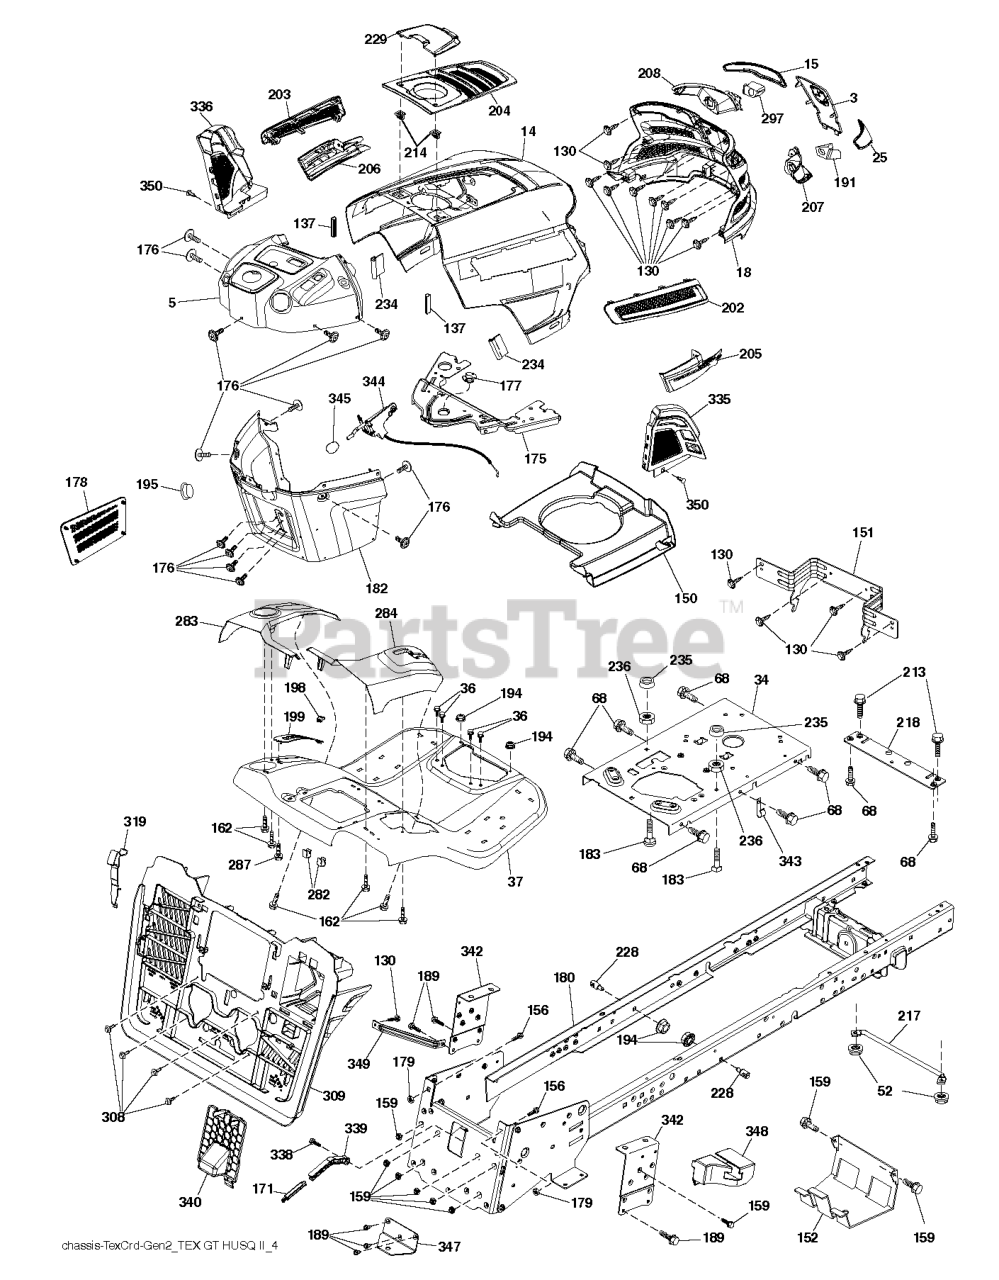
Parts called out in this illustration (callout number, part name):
3	APPLIQUE.SUBASM.GT.HUSQ.II
5	DASH.UPP.GT2.SM.PTO.MC.HR.GREY
14	HOOD.ASM.HUSQVARNA.GT.TEX.ORAN
15	LENS.HEADLIGHT.LH.GTII.2011
18	GRILLE.SUBASM.GT.HUSQ.II
25	LENS.HEADLIGHT.RH.GTII.2011
34	PLATE.ENGINE.WELDED.CHASSIS
36	SCREW 5/16"
37	FENDER.TEX.SRD.CRD.BASE
52	LOCKNUT
68	SCREW LT
130	SCREW.#10 X 0.750.BOS
137	BUMPER DASH
150	AIR DUCT.GTV2(1.66"RING HEIGHT
151	BRACKET.PIVOT.HOOD.GT.HUSQ.II
152	SHIELD.BROWNING.PNT.GT.V2
156	BOLT
159	SCREW, 3/8-16X3/4
162	SCREW.HI-LO.CONSOLE
171	EXTENSION.BAGGER.FULL.
175	PLATE.CROSSMEMBER.HUSQ
176	SCREW.#10-24X5/8.RN.QU
177	BUSHING, STEERING
178	CARGO.ASM.NET.TXGT.W/C
182	DASH DASH LOWER
183	BOLT.5/16-18X1-1/4 FULL THD
189	SCREW
191	INSERT.REFLECTIVE.RH.HUSQ.GTII
194	NUT LOCK HEX FLANGE 5/16-18
195	PLUG.HOLE.DASH.LOWER.12V.BLK
198	INDICATOR.DECK.LIFT.RED
199	PLATE DECK LIFT
202	VENT.SIDE.RH.GT.HUSQ.II.
203	VENT.SIDE.LH.GT.HUSQ.II.498
204	VENT.TOP.EXTERNAL.FILL.GT2.GRE
205	SIDE.TRIM.RH.GT.HUSQ.II
206	SIDE.TRIM.LH.GT.HUSQ.II.GRAY
207	BEZEL LIGHT.RH.GT.II.MYLAR
208	BEZEL LIGHT.LH.GT.II.MYLAR
213	BOLT
214	CLIP.RETAINER.TINNER.
217	ROD.PIVOT.HOOD
218	X-PIECE.HOOD.STOP.NON/
228	STUD.FASTNER.W/ANTI-ROTATE
229	LID.EXT.FILL.GT.HUSQ2.BLACK
234	BUMPER.HOOD.TEX.HUSQVARNA
235	SPACER FENDER
236	NUT.CENTERLOCK.5/16-
282	CLIP.RETAINER.CONSOLE.LT.HUSQ
283	CONSOLE.DECKLIFT.CRDII.498
284	CONSOLE.PEDAL.HYDRO
287	SCREW 1/4X20
297	INSERT.REFLECTIVE.LH.HUSQ.GTII
308	BOLT.5/16-18UNCX3/4 W/SEMS.BLK
335	COVER.LOWER.DASH.RH.BLACK
336	COVER-LH.LOWER.DASH.GT2.BLACK
338	BOLT BOLT SHOULDER
339	LEVER.BAGGER.FULL.TEX.
342	SUPPORT SUPPORT FENDER
343	CLIP CLIP
344	CONTROL.EZ.MULCH.TEX/CRD
345	RP KNOB.OVAL.TAPERED.3/8-16BLK
347	HITCH TOW
349	BRACKET.SUPPORT.LRVB/CRD
350	CLIP.X-MAS.TREE
